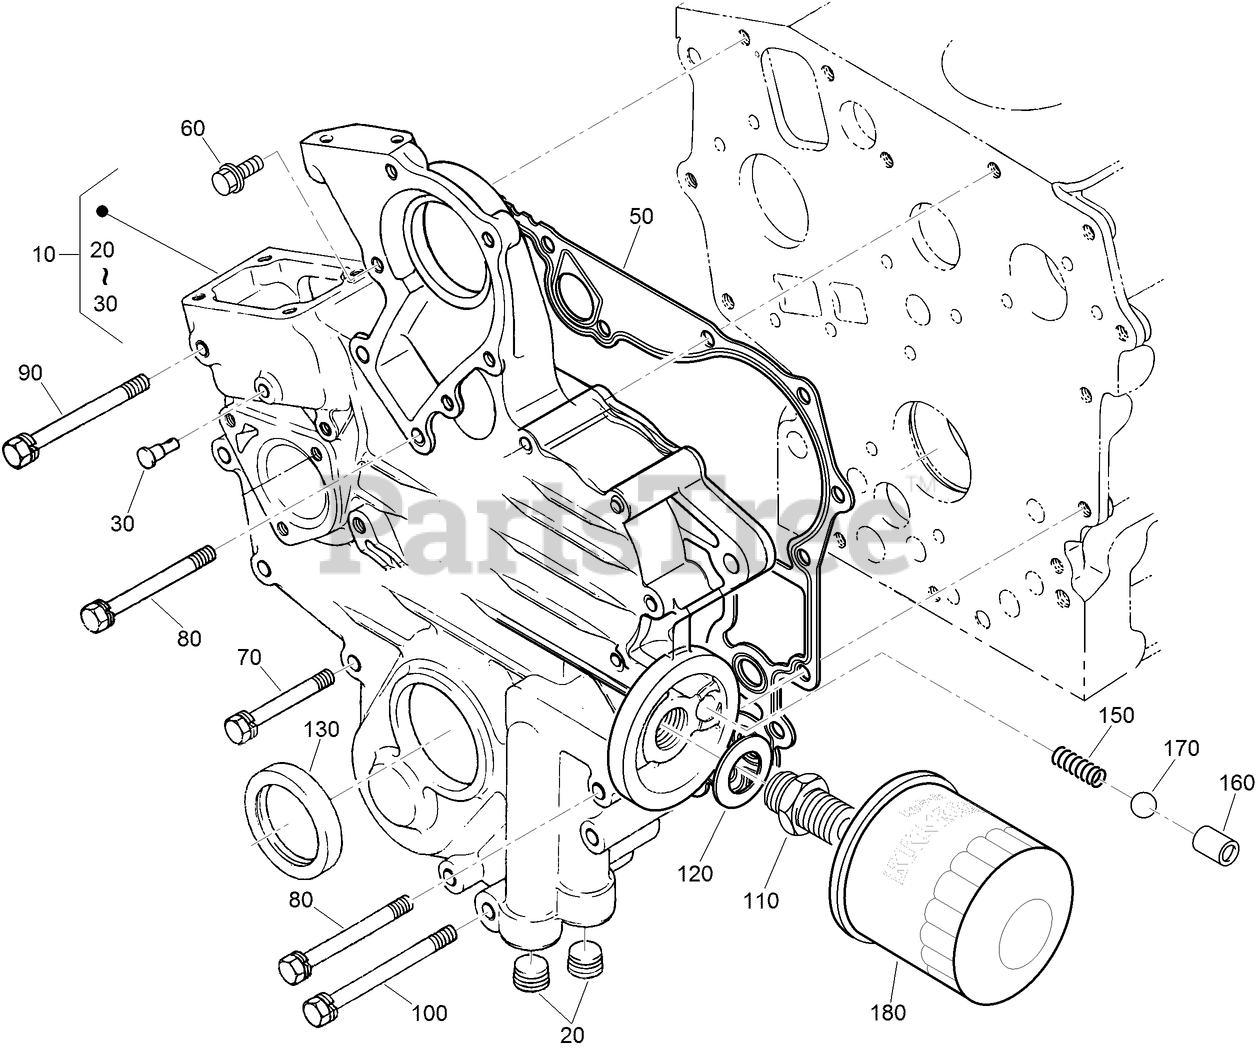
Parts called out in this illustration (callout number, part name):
10	GEAR CASE ASM
30	PIN-SPRING, START
50	GASKET-CASE, GEAR
60	BOLT-FLANGE
70	BOLT-SEMS
110	JOINT-PIPE
120	WASHER-PLAIN
130	SEAL-OIL
150	SPRING
160	SEAT-VALVE
180	FILTER-OIL, ENGINE
